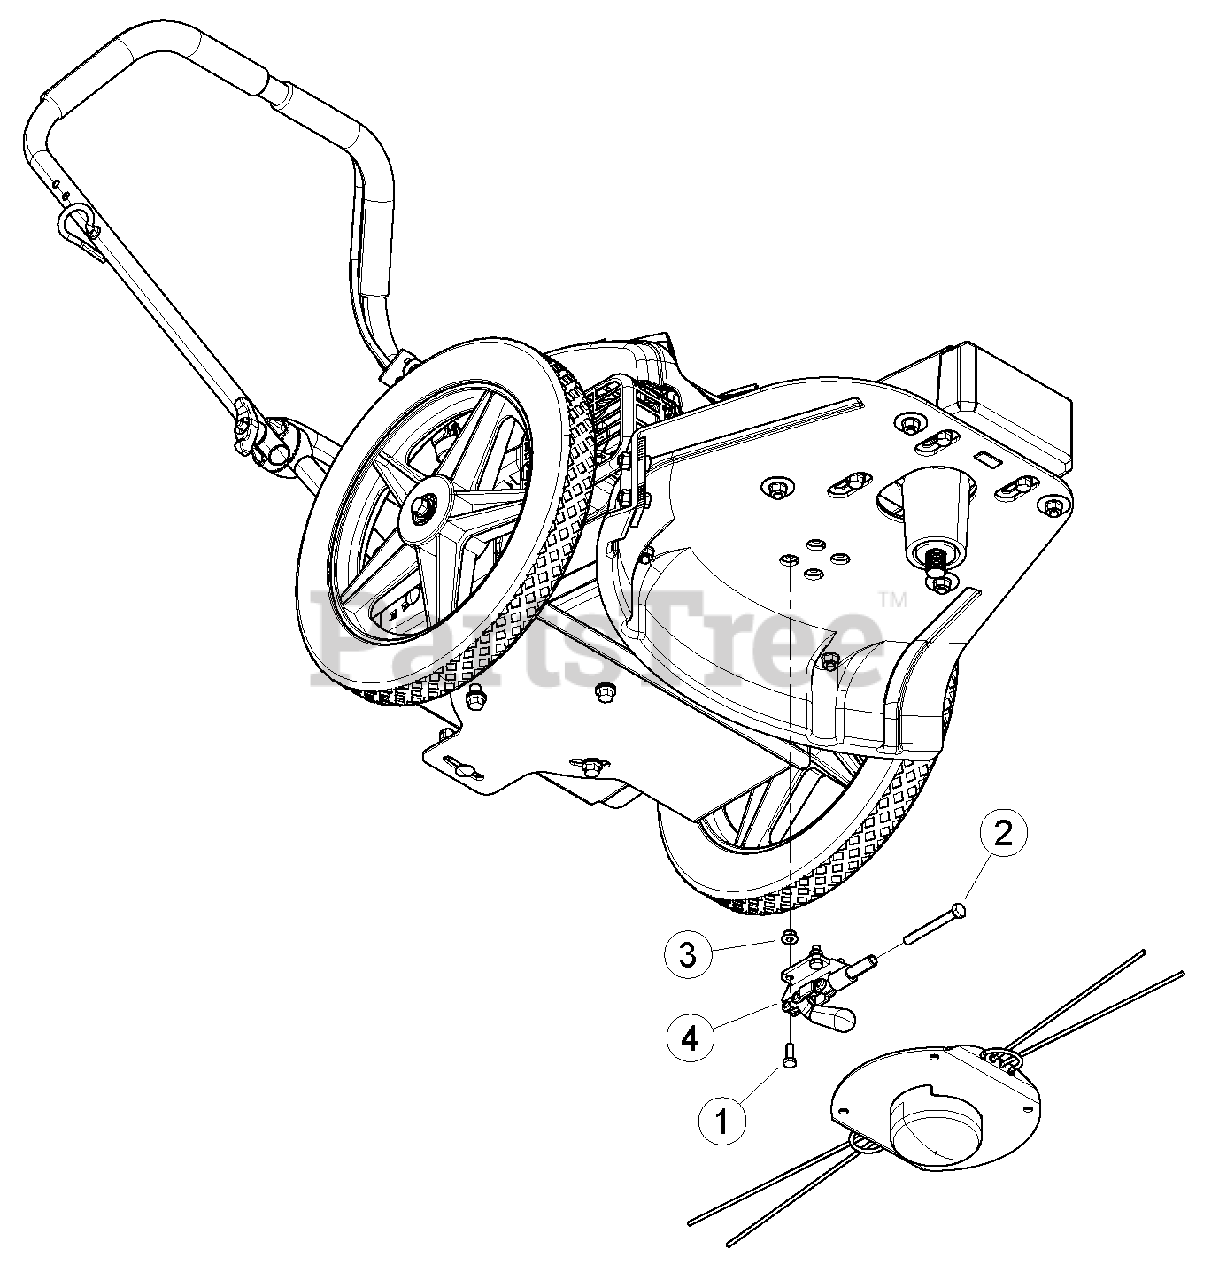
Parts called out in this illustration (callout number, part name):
1	BOLT, 1/4 X 3/4 HEX HD
2	BOLT, 5/16 NCX 2-3/4 GR5 HCPS ZP
3	NUT, 1/4-20 NYLOCK FLANGE
4	CLAMP, STRAIGHTLINE 600 LB
